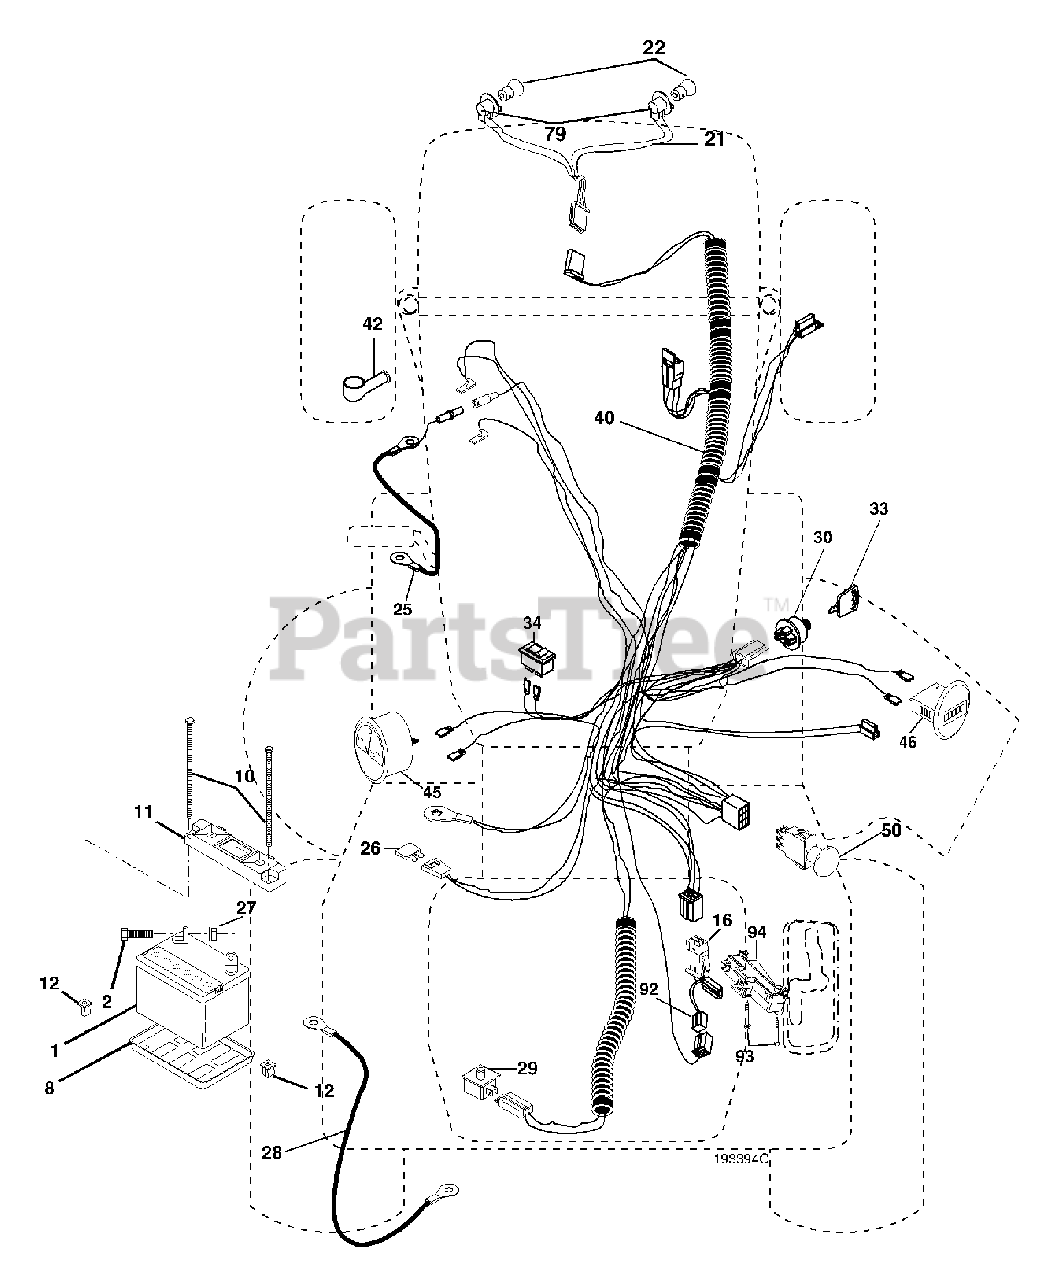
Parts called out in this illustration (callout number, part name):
1	Battery
2	Bolt Hex Head 1/4-20 x 3/4
8	Tray, Battery
10	Bolt, Battery Front 1/4-20 x 7.5 Zinc
11	Holddown Battery Front Mount
12	Nut, Push Nylon 1.4" Battery Front
16	Switch Interlock Push-In
21	Harness Socket Light w/4152J
22	Bulb Light
27	Nut Keps Hex 1/4-20
28	Cable Bolt Ground
29	Switch, Seat
30	Switch, Ign
34	Switch Light/Reset B/B/Red
40	Harness Ign.
42	Cover, Terminal Red
50	Switch, PTO
79	Bulbholder Asm
92	Harness Pigtail Reverse Switch
93	Screw 10-14 x 2.0
94	Modual Reverse ROS
